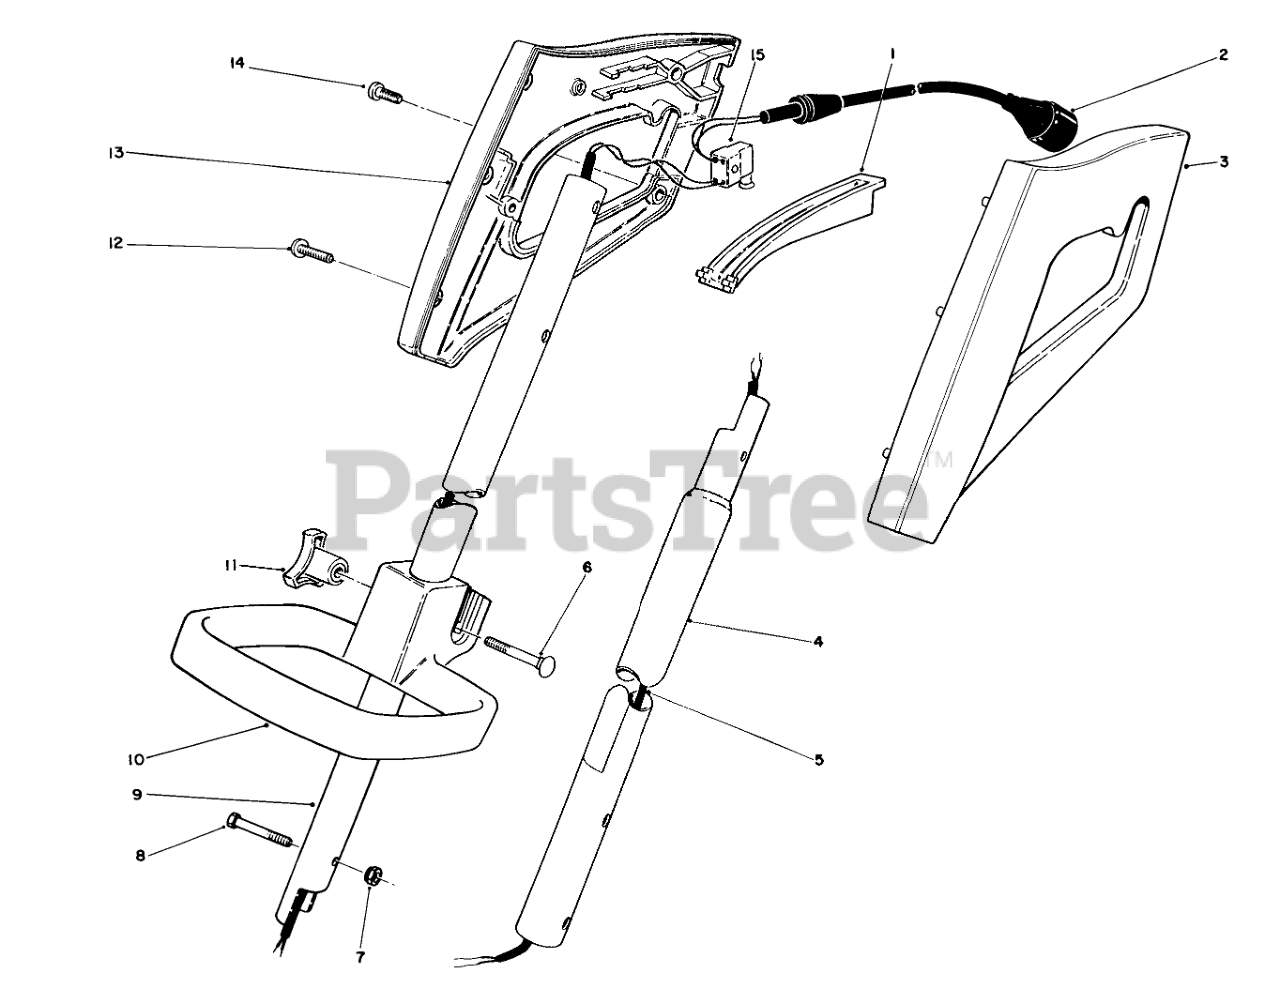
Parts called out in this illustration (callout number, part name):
1	TRIMMER-SWITCH BAR
2	Cord-Power
3	HANDLE GRIP, LH
4	1100 LOWER EXT. TUBE
5	WIRING HARNESS
6	BOLT-CARR
7	NUT-LOCK, NI
8	HEX HD MACHINE SCREW
9	TUBE-UPPER
10	Handle-Adjust
11	HANDLE KNOB
12	Screw
13	HANDLE GRIP, RH
14	SCREW-PPH
15	SWITCH
